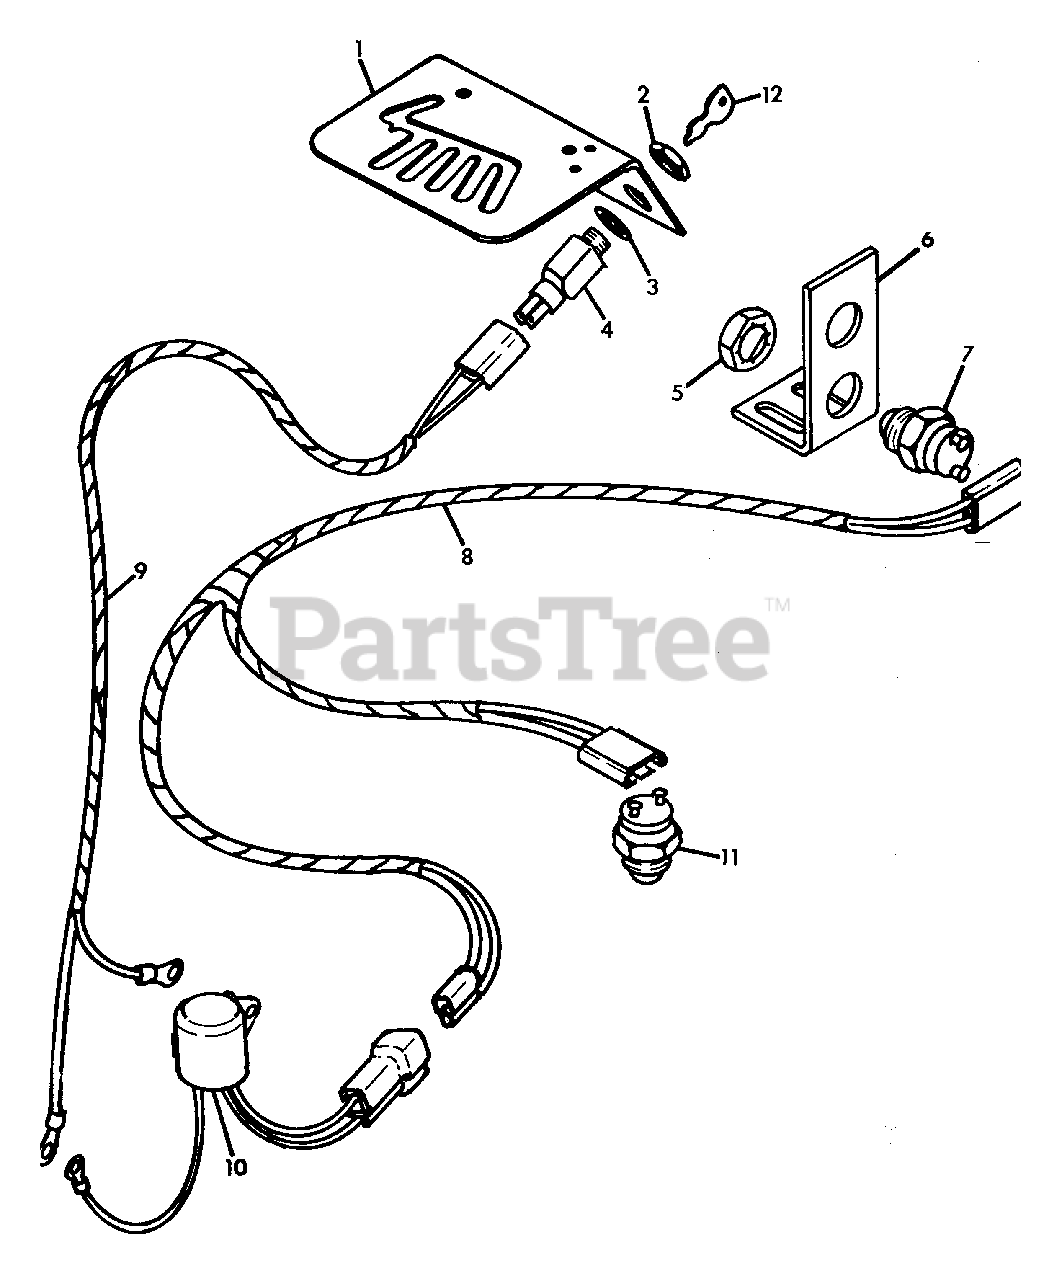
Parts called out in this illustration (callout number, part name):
1	Plate, Instruction
2	Nut, Jam 5/8-32
3	Washer, Lock 5/8
4	Switch, Key
5	Nut, 9/16-18
6	Bracket, Interlock Switch
7	Switch, Interlock
8	Harness, Wiring Interlock
9	Harness, Wiring Switch
10	Control Module
11	Switch, Neutral Start
12	Key, Ignition Switch
